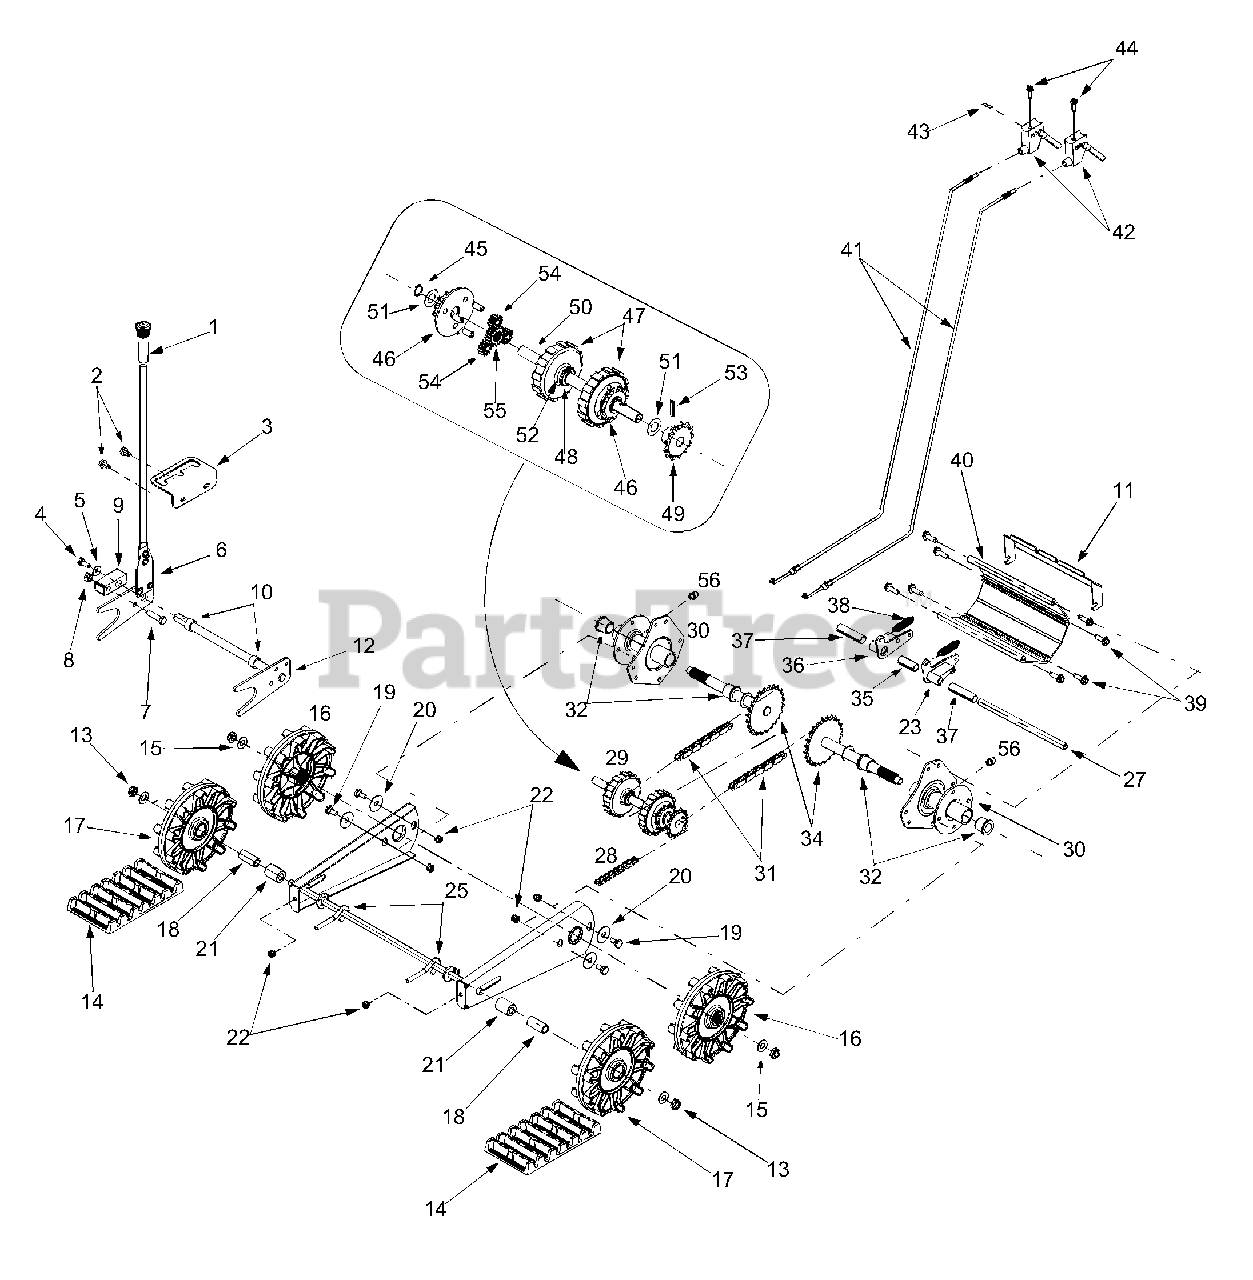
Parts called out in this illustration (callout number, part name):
2	Tap Screw, 5/16-18 x .625
4	Hex Cap Screw, 5/16-24 x .75
5	Bell Washer, .34 ID x .872 OD
7	Hex Cap Screw, 3/8-24 x 1.5
8	Hex Nut, 3/8-24
9	Lift Shaft Drive
10	Spacer, .628 ID x .875 OD x .5
13	Jam Nut, 1/2-20
14	Snow Track
15	Flat Washer, .5 x 1 x .06
16	Track Drive Wheel
17	Track Idler Wheel
18	Spacer, .51 ID x .75 OD x 1.67
19	Screw, .435 x .178-5/16 x .56
20	Flat Washer, .442 x 1.38 x .06
21	Spacer, .51 ID x 1 OD x 1.34
22	Hex Nut, 5/16-18
23	LH Dogg Assembly
25	Eye Bolt, 5/16-18 x 3
27	Actuator Shaft
28	Chain
29	Track/Steering Shaft Assy
31	Chain
32	Flange Bearing
34	Axle Assembly
35	Spacer, .514 x .630 x 1.59
36	RH Dogg Assembly
37	Spacer, .514 x .630 x 2.44
38	Ext. Spring
39	Tap Screw, 5/16-18 x 1
40	Track Housing
41	Steering Cable
42	Steering Trigger
43	Flange Nut
44	Screw, #10-24 x 1.375
45	Retaining Ring
46	Carrier Assembly
47	Ring Gear
48	Retaining Ring
49	13-Tooth Sprocket
50	Track Steering Drive Shaft
51	Flat Washer, .58 x 1.06 x .02
52	Flat Washer, 5/8 x 1 x .03
53	Spiral Pin, 3/16 x 1
54	12-Tooth Gear
55	18-Tooth Gear
56	Grease Fitting
